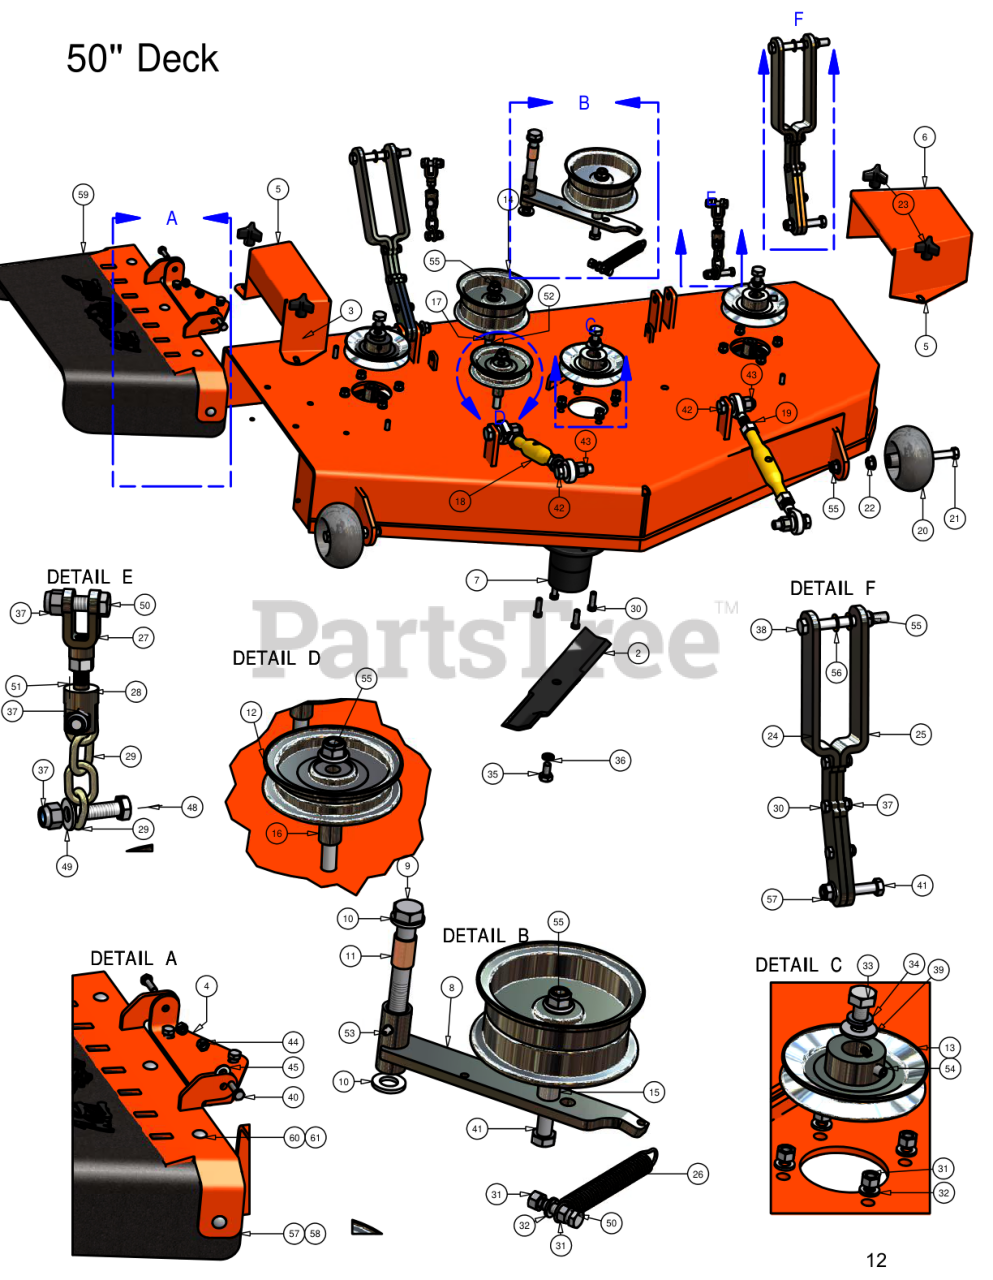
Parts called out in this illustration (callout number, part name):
1	50" Deck Belt
2	50" Fusion Blade
4	Discharge Chute Hanger
5	Spindle Cover
6	Spindle Cover
8	Deck Idler Arm
9	5/8" x 4" Hex Bolt
10	.635 ID Plastic Washer
11	5/8" ID x 1 1/8" Brass Bushing
12	4 3/4" Idler Pulley
13	5" Deck Pulley
14	5 3/4" Deck Idler Pulley
15	1 1/4" Pulley Spacer
16	1 1/2" Pulley Spacer
17	1 3/4" Pulley Spacer
18	Turnbuckle
19	3/4" Left Handed Nut
20	Anti-Scalp Rollers
21	1/2" x 4" Bolt (Grade 8)
22	1/2" Flange Nut
23	5/16" Knob
24	Deck Support Arm (left)
25	Deck Support Arm (Right)
26	Deck Idler Spring
27	Female Yoke
30	3/8" x 1 1/4" Hex Bolt
31	3/8" Hex Nut
32	3/8" Lock Washer
33	1/2" x 1 1/2" Bolt Fine Threaded
34	1/2" Lock Washer
35	5/8" x 1.5" Fine Threaded Bolt
36	5/8" Lock Washer
37	3/8" Nylock Nut
38	1/2" x 4 1/2" Bolt
39	1/2" Cup Washer
40	5/16" x 1" Hex Bolt
41	1/2" x 2 1/2" Hex Bolt
42	5/8" x 2 1/2" Hex Bolt
43	5/8" Nylock Nut
44	5/16" Nylock Nut
45	.360 ID Plastic Washer
46	3/8" x 3/4" Hex Bolt
47	3/8" Flange Nut
48	3/8" x 1" Hex Bolt
49	3/8" Flat Washer
50	3/8" x 1 1/2" Hex Bolt
51	3/8" Fine Threaded Jam Nut
52	1/2" x 3 1/2" Bolt
53	Grease Fitting (Drive-In Type)
54	3/8" Set Screw
55	1/2" Flange Lock Nut
56	1/2" Brass Washer
57	2007 Hanger Plate
58	2007 Lower Hanger Plate
59	Rubber Side Discharge
60	5/16" x 1 1/2" Carriage Bolt
